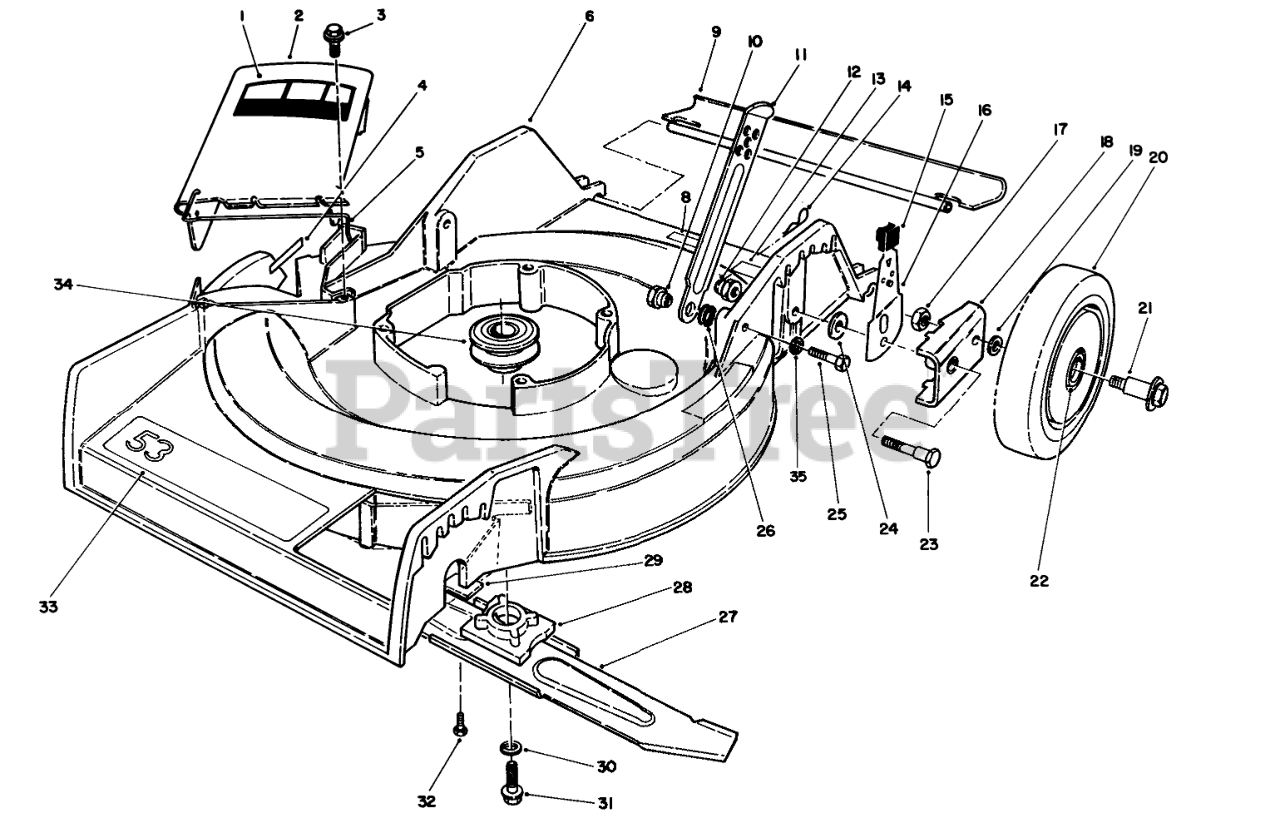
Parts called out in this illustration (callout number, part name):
1	DECAL - DANGER DEFL
2	Deflector (Incl. Ref. #1 & 5)
3	SCREW-HWH
4	DANGER DECAL
5	SPRING HINGE
6	Housing (Incl. Ref. #4)
8	DECAL FRENCH REGUL.
9	SHIELD - TRAILING
10	HANDLE PIVOT NUT
11	HANDLE LATCH
12	HANDLE PIVOT NUT
13	Decal-Noise
14	PIN-COTTER, HAIR
15	KNOB-ARM
16	SPRING ARM ASSEMBLY
17	Nut
18	HP PIVOT ARM ASM
19	WASHER
20	Wheel & Tire Assembly (Incl. Ref. #22)
21	BOLT-WHEEL
22	BUSHING
23	PIVOT SCREW
24	PIVOT WASHER
25	SCREW-HH
26	SPACER
27	Blade
28	BLADE RETAINER
29	FRONT SHIELD
30	WASHER-LOCK
31	SCREW-HH
32	SCREW-HWHTF
33	DECAL - SP DECK
34	PULLEY-DRIVER
35	WASHER-LOCK
